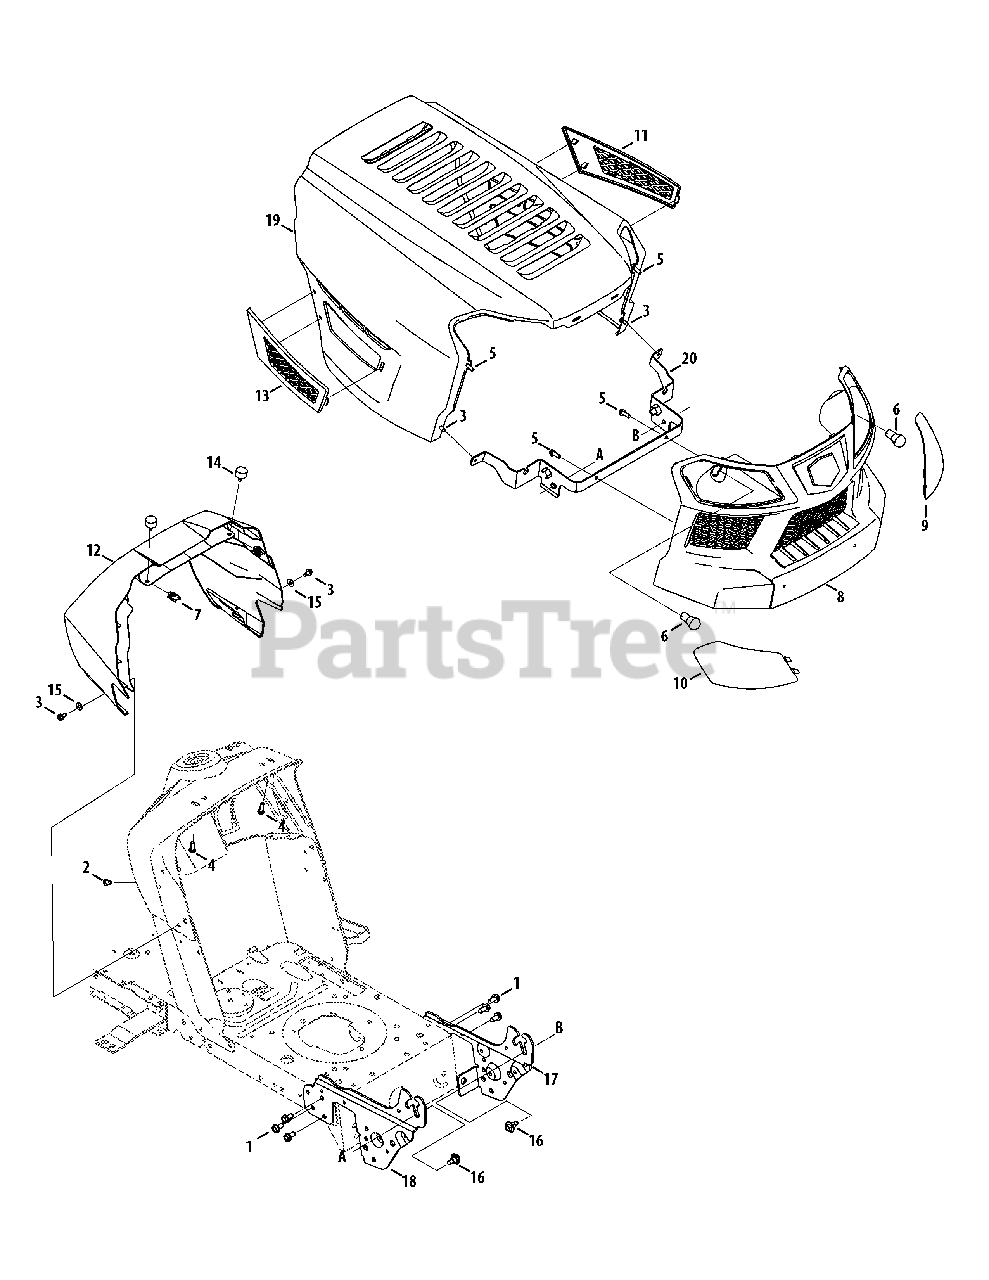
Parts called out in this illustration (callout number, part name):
1	Screw, 5/16-18 x .750
2	Self-Tap Screw, 1/4-20 x .5
3	Self-Tap Screw, 1/4-20 x .625
4	Self-Tap Screw, 1/4-20 x .75
5	Plastic Screw, 1/4-10 x .75
6	Headlight Bulb
7	U-Clip Nut
8	CPX Grill
9	Grill Lens, LH
10	Grill Lens, RH
11	Side Cover, LH
12	Dash Collar
13	Side Cover, RH
14	Bumper, .70 DIA X .53
15	Flat Washer, .25 X.630 X.0515
16	Shoulder Screw, .43 x .29, 5/16-18
17	Pivot Support Bracket, LH
18	Pivot Support Bracket, RH
19	Hood
20	Grill Pivot Bracket
